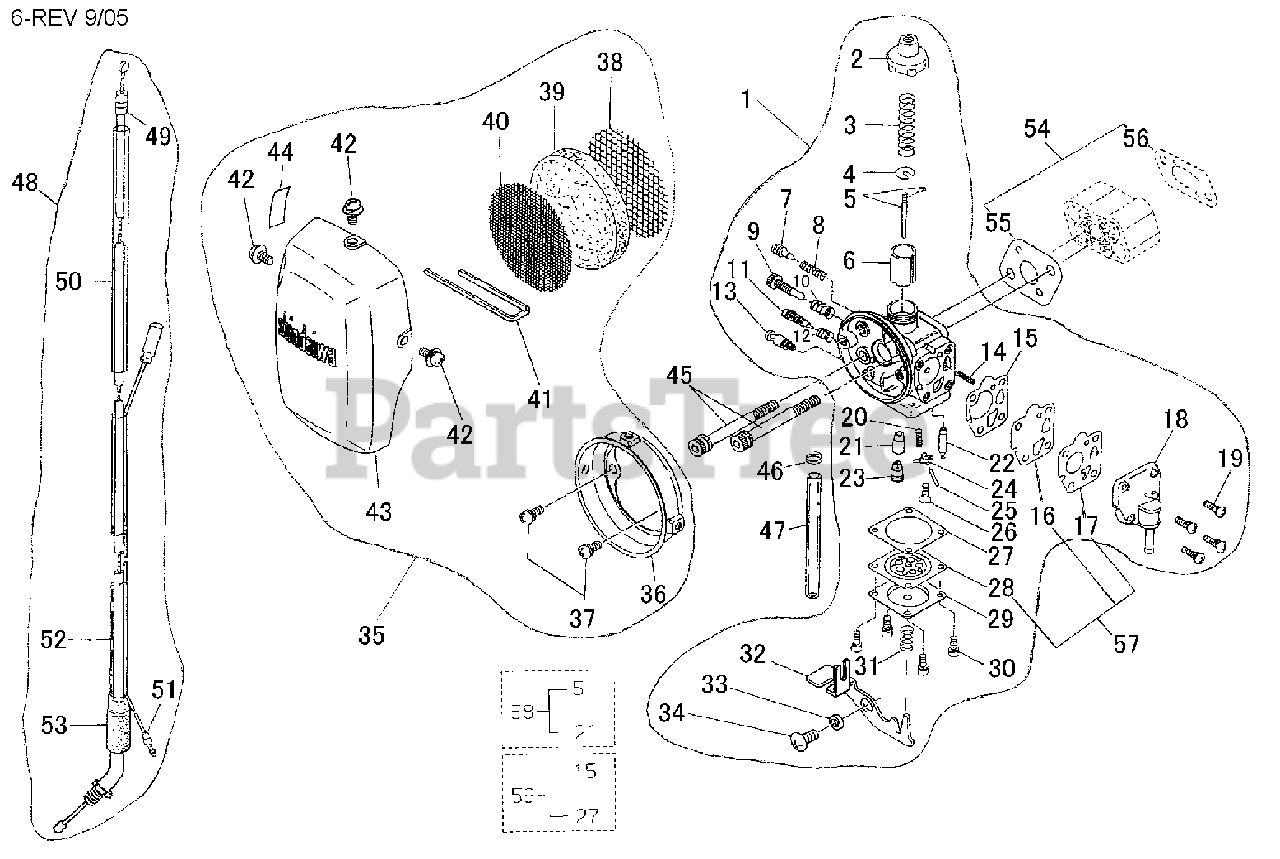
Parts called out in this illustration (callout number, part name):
1	CARBURETOR
2	CAP, THROTTLE
3	SPRING
4	WASHER, SPRING SUPPORT
5	NEEDLE, JET
6	VALVE, THROTTLE
7	SCREW, SLOW AIR
8	SPRING
9	SCREW, IDLE ADJUST
10	SPRING
11	SCREW, MAIN ADJUST
12	SPRING
13	VALVE, OVERFLOW
14	SPRING, COIL
15	GASKET, DIAPHRAGM
16	DIAPHRAGM, METERING
17	VALVE, PUMP
18	BODY, PUMP
19	SCREW
20	SPRING
21	JET, MAIN
22	VALVE, INLET NEEDLE
23	HOLDER, MAIN JET
24	LEVER, METERING
25	PIN, METERING LEVER
26	SCREW M3×8
27	GASKET
28	DIAPHRAGM, METERING
29	COVER, DIAPHRAGM
30	SCREW M3×8
31	SPRING
32	LEVER, TICKLER
33	COLLAR
34	SCREW
35	AIR FILTER ASSY
36	CASE, AIR FILTER
37	SCREW
38	SCREEN, REAR
39	FILTER, AIR
40	SCREEN - FRONT
41	CLIP, FILTER RETAINING
42	SCREW 4
43	COVER, AIR FILTER
44	LABEL, CHOKE
45	BOLT M5×50
46	CLIP Ø6
47	PIPE, FUEL
48	CABLE ASSY, CONTROL
49	CABLE, THROTTLE
50	TUBE, THROTTLE CABLE
51	LEAD
52	TUBE, PROTECTIVE
53	CAP, CARBURETOR
54	GASKET KIT, INTAKE
55	GASKET, CARBURETOR
56	GASKET, INTAKE
57	DIAPHRAGM KIT
58	NEEDLE KIT, JET
59	GASKET KIT
